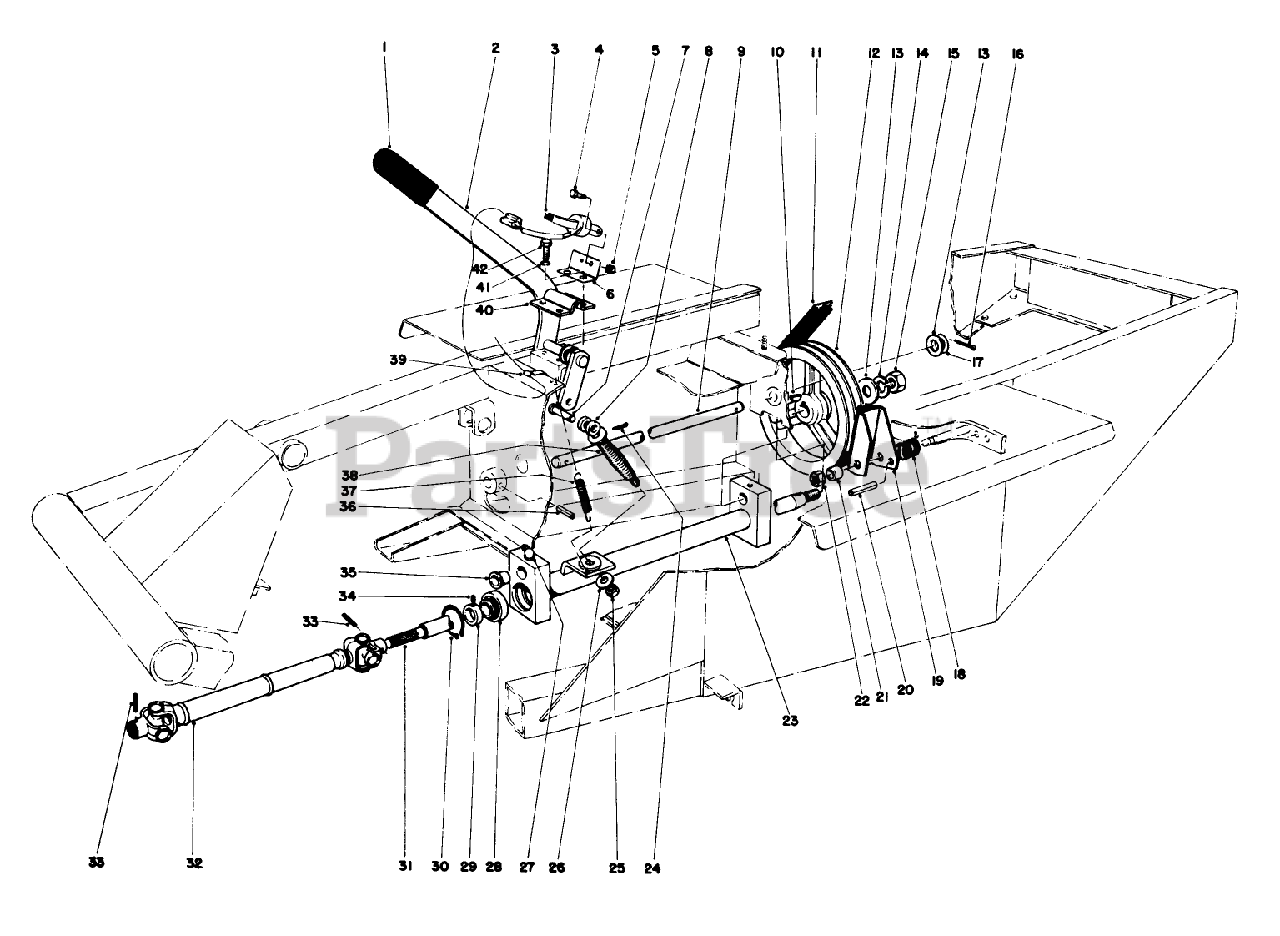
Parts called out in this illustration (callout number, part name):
1	GRIP-HANDLE
2	Lever P.T.O.
3	SWITCH ARM
4	SCREW-HH
5	NUT-LOCK, NI
6	SWITCH ARM MT
7	PIN-CLEVIS
8	YOKE END WA R
9	PIVOT PTO SHAFT
10	KEY-WOODRUFF
11	V-Belt
12	PULLEY-PTO
13	WASHER-FLAT
14	WASHER-LOCK, INT
15	NUT-HEX
16	PIN-COTTER
17	WASHER-THRUST
18	SPRING-ADJUSTMENT
19	PTO BRAKE ASM
20	PIN-ROLL
21	SPACER-SPRING, ANCHOR
22	NUT-LOCK, NI
23	Pivot-Power Take Off (Incl. Ref. #35)
24	PIN-COTTER
25	NUT-LOCK, NI
26	Washer
27	FITTING-GREASE
28	Bearing
29	Lock Collar (Incl. Ref. #34)
30	RING-SNAP, INTERNAL
31	PTO SHAFT
32	Universal Joint
33	PIN-ROLL
34	SCREW-SET, HSH
35	3/4IDX1LG FLANGE BSHG
36	PIN-ROLL, SLOTTED
37	SPRING-EXTENSION
38	SPRING-COMPRESSION
39	CLAMP-CASING
40	CLAMP-LEVER, PTO
41	WASHER-LOCK
42	SCREW-HH, TAP
